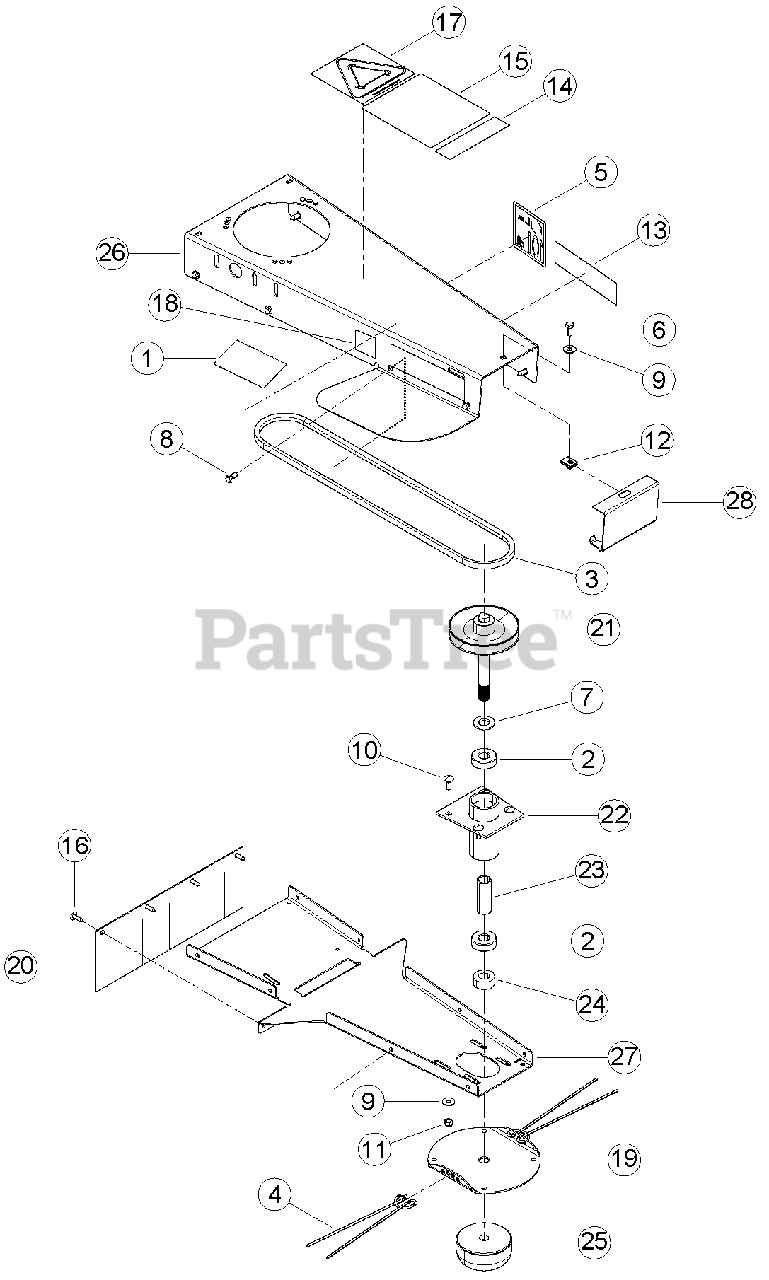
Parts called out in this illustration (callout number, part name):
1	DECAL, GRINDER DANGER
2	BEARING, 3/4 BALL
3	BELT, 4L 53 ARAMID
4	STRING, .155 X 20-1/2
5	DECAL, 101 DB
6	BOLT, 5/16 X 3/4 HEX HD GR5 ZP
7	WASHER, 3/4 SAE FLAT ZP
8	SCREW, 11/32 X 7/8 HWH AB THREAD ZP
9	WASHER, 5/16 FLAT ZP
10	BOLT, 5/16 X 7/8 CRG GR5 NC ZP
11	NUT, 5/16 NE NYLOCK ZP
12	NUT, 5/16-18 TINNERMAN U-TYPE
13	DECAL, ECHO BEARCAT 6.82 X 1.90
14	DECAL, MODEL WT190
15	DECAL, MANUAL/SAFETY INFO
16	RIVET, PLASTIC 1/4 X 7/8
17	DECAL, RECLAIM IT
18	DECAL, ECHO BEAR CAT QR CODE
19	DISK, TRIMMER HEAD
20	FLAP, TRIMMER
21	WELDMENT, TRIMMER PULLEY
22	WELDMENT, SPINDLE HUB
23	SPACER, TRIMMER SPINDLE
24	SPACER, TRIMMER HEAD
26	BODY, TRIMMER
27	BOTTOM, TRIMMER FRAME
28	COVER, FRONT TRIMMER
